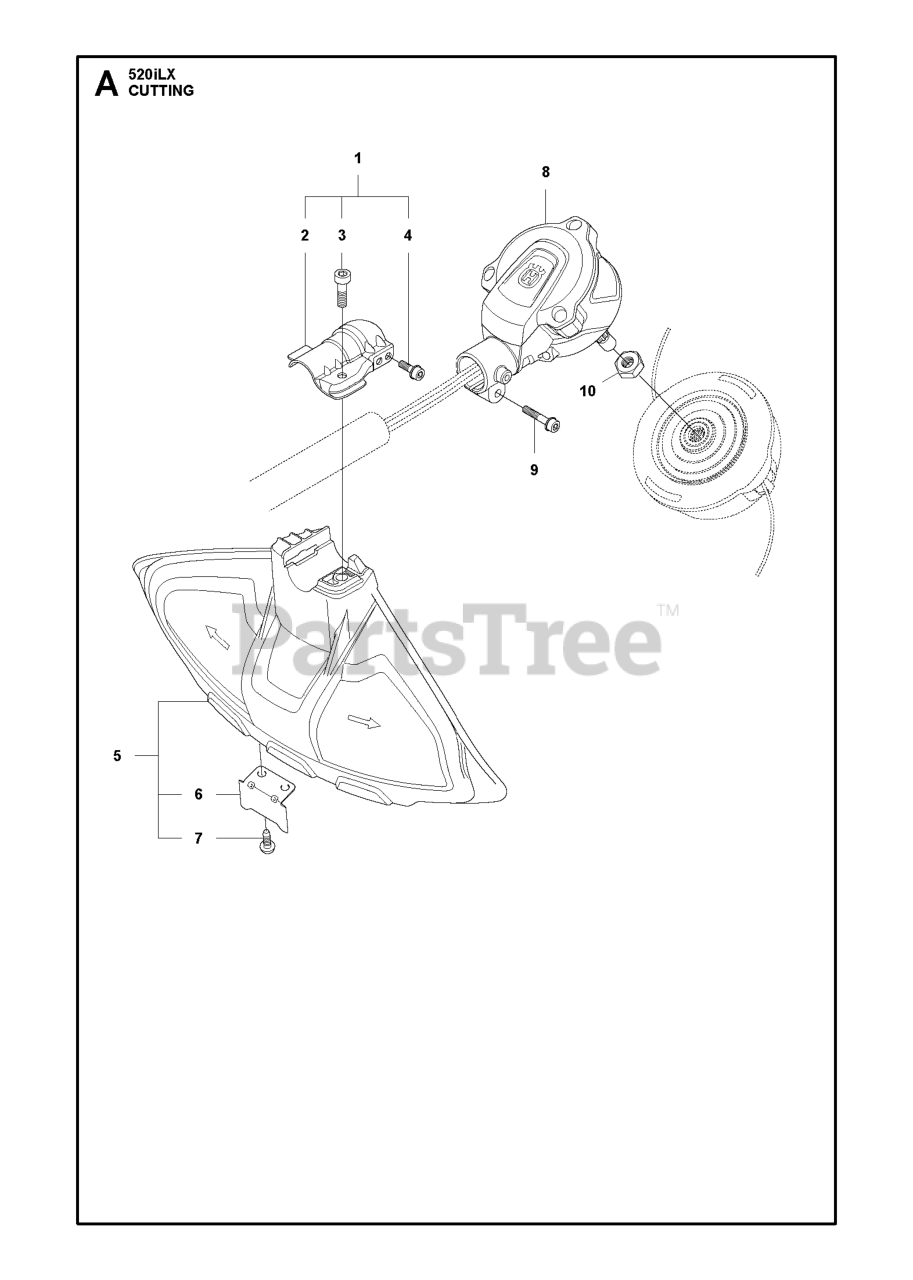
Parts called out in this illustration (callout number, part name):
2	RP BRACKET TRIMMER GUARD
3	SCREW IHSCM M6X22 10.9 ZN/FE
5	TRIMMER SHIELD ASSY
6	LINE LIMITER
8	MOTOR ASSY BLDC BLADE
10	GEARHEAD NUT - BRUSHCUTTER
